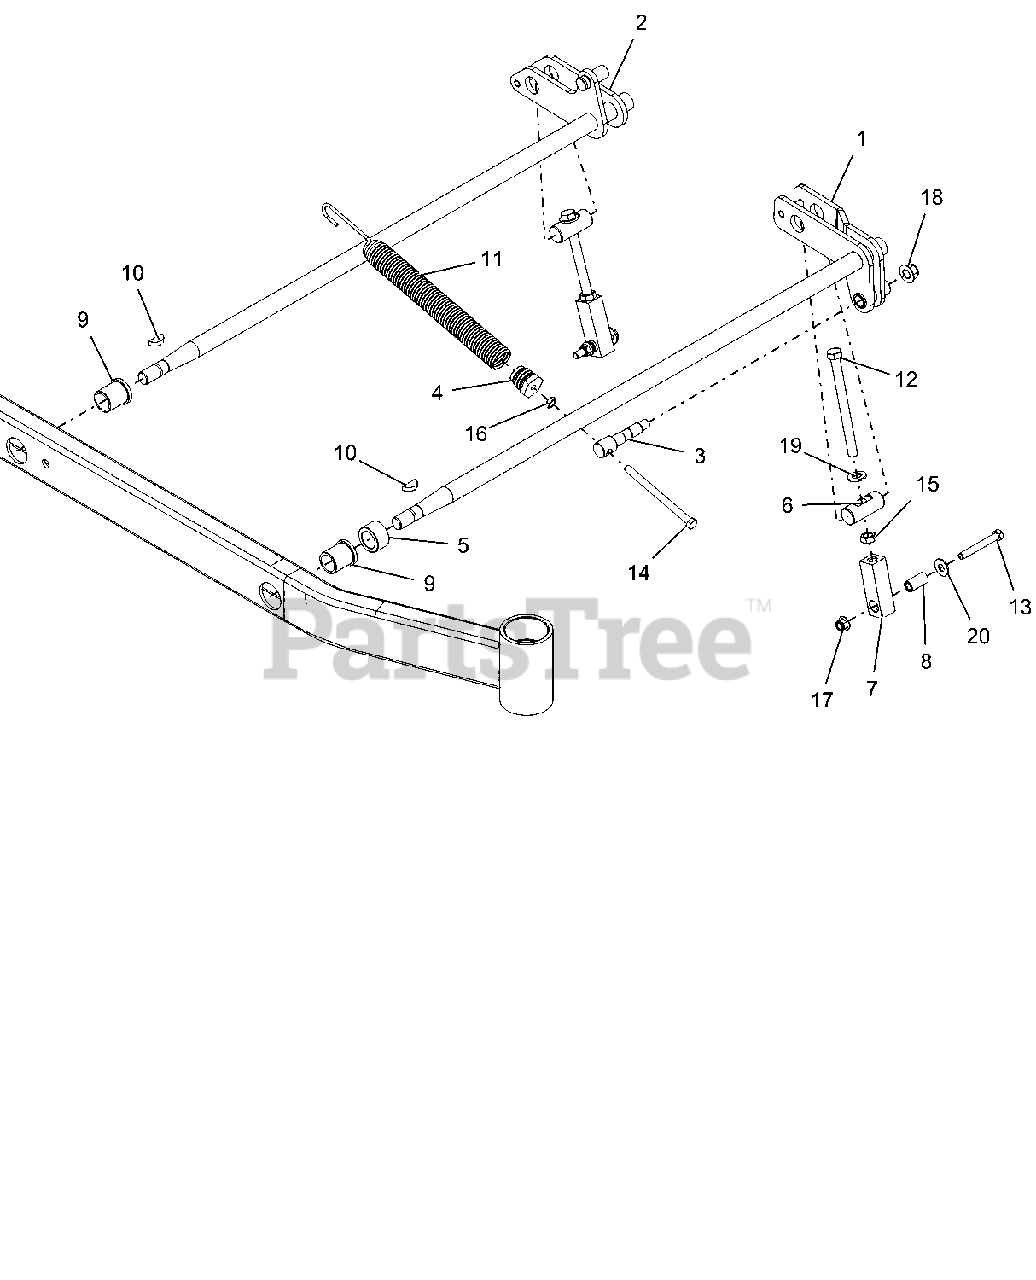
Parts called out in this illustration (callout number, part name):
1	FRONT LH DECK LIFT ARM WMT-LF
2	WLM, REAR LH DECK LIFT ARM-LF
3	TRUNION, DECK LIFT SPRING
4	PLUG, SPRING
5	SPACER, 1.500 X 1.000 X .880
6	PIN, DECK LIFT
7	LINK, DECK LIFT
8	SPACER, DECK LEVELING
9	BSHG-FLG 1.00X1.25X1.50X1.50
10	KEY-WDRF .25X1.00 HRD #15
11	SPRING, DECK LIFT
12	BOLT,.50-13X6.00-2.50 LG THD
13	BLT-HEX .38-16X2.75 GR8 YWZC
14	BLT-HEX .38-16X5.00 GR5 FTH YZ
15	NUT-JAM .50-13 YWZC
16	NUT-HEX-JAM .375-16 YWZC
17	@NUT-LK-NYL-FLG .38-16 YWZC
18	@NUT-LK-NYL-FLG .50-13 YWZC
19	FLATWASHER 1/2 SAE HARD 15906
20	@WSHR-FL-STL.438X1.00X.083 YWZ
